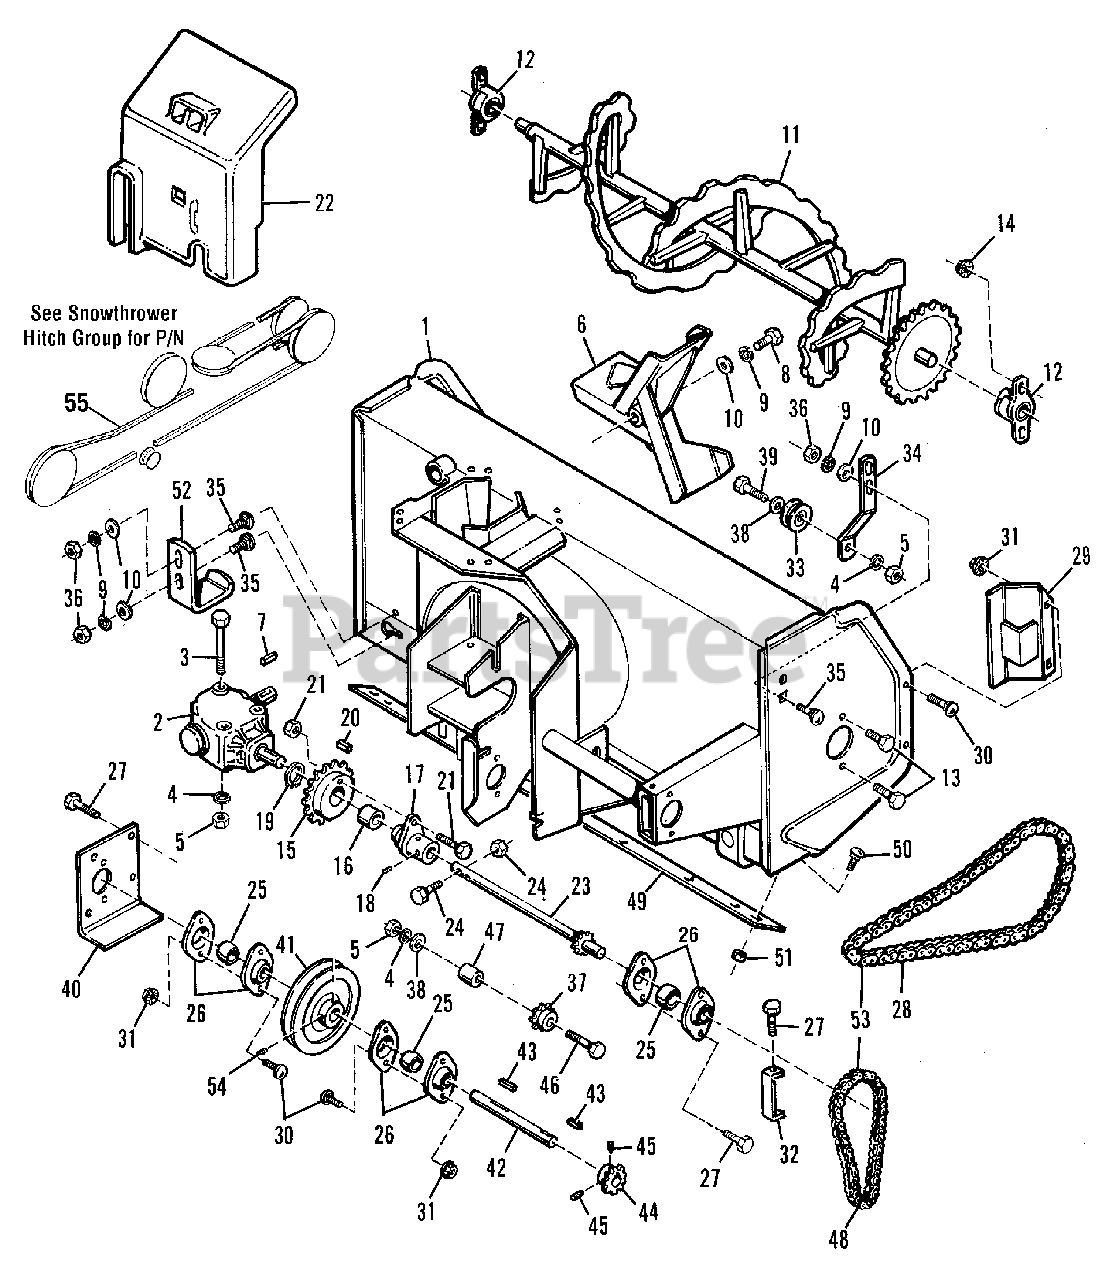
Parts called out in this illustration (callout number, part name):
1	FRAME ASSEMBLY
3	CAPSCREW, Hex Head, 3/8-16 x 4
4	LOCKWASHER, 3/8
5	NUT, Hex, 3/8-16
6	FAN ASSEMBLY.
7	KEY, 8mm x 7mm x 35mm
8	CAPSCREW, Hex Head, M8-1-1/4 x 25mm
9	LOCKWASHER, 5/16
10	WASHER, Plain, 5/16
12	BUSHING, Side Mount
13	SCREW, Hex Head, Whizlock, 3/8-16 x 3/4
14	NUT, Hex, Flange Lock, 3/8-16
17	SHEAR PLATE
18	SETSCREW, Square Head, Cup Point, 5/16-18 x 5/16
19	SNAP RING, External
20	KEY, 8mm x 35mm
21	SHEAR BOLT, Fan, w/Nylon Nut, 5mm x.8 x 40mm
22	COVER, Reduction, Plastic
23	SHAFT, Driven
24	SHEAR BOLT, Auger, w/Nylon Nut, 5mm x.8 x 45mm
26	BEARING, Flange
27	SCREW, Hex Head, Whizlock, 5/16-18 x 1/2
28	CHAIN, #40 x 91 Links (without connecting link)
29	GUARD, Chain, Auger
30	CARRIAGE BOLT, 5/16-18 x 5/8
31	NUT, Hex, Flange Lock, 5/16-18
32	GUARD, Chain, Drive Shaft
33	PULLEY, Idler
34	ARM, Chain Adjuster
35	CARRAIGE BOLT, 5/16-18 x 1
36	NUT, Hex, 5/16-18
37	SPROCKET, Idler
38	WASHER, Plain, 7/16
39	CAPSCREW, Hex Head, 3/8-16 x 1-3/4
40	PLATE, Support Bearing
41	PULLEY ASSEMBLY, (Incl. Ref. No. 54)
42	SHAFT, Driving
43	KEY, 3/16 x 3/16 x 1
45	SET SCREW, Square Head, Cup Piont, 1/4-20 x 5/16, G8
46	CAPSCREW, Hex Head, 3/8-16 x 2-3/4
47	SPACER, Idler
48	CHAIN, #40 x 40 Links (Incl. Ref. No. 53)
49	EDGE, Cutting
50	CARRIAGE BOLT, 5/16-18 x 3/4
51	NUT, Hex, Centerlock, 5/16-18
53	MASTER LINK, Chain #40
54	SET SCREW, Square Head, Cup Piont, 5/16-18 x 3/4, G8
55	BELT, Snowthrower Drive
